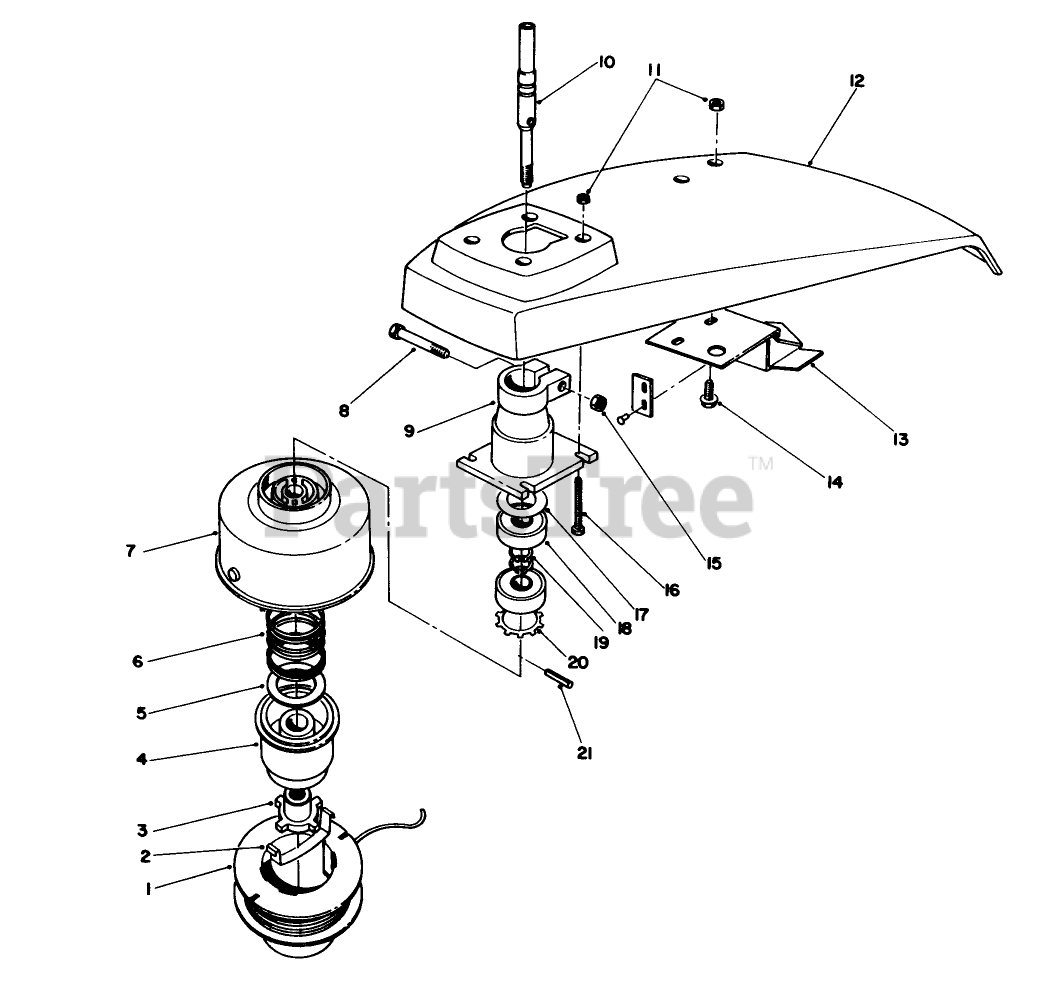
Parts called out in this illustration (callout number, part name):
3	DRIVER
4	SPOOL CORE
5	WASHER-FLAT
6	SPRING COMPRESSION
7	DRUM/EYELET
8	SCREW-HH
10	Shaft-Power
11	NUT-LOCK, NI
14	SCREW-HWH
15	NUT-LOCK, NI
16	SCREW-HH
17	Washer
18	Ball Bearing
19	Snap Ring
20	Grip-Spring
